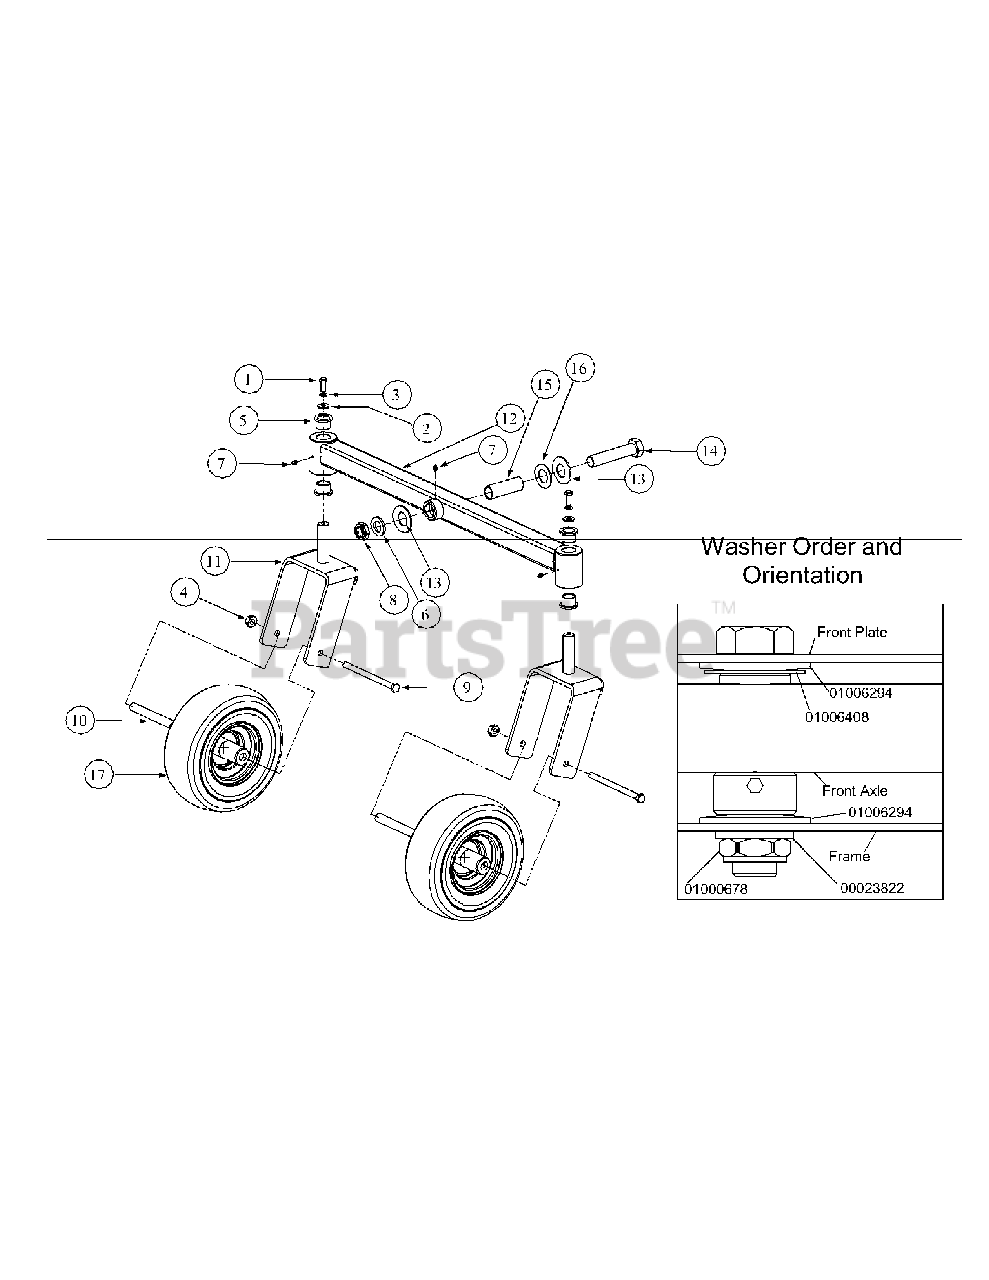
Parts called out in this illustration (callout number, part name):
1	Hex Cap Screw, 3/8-16, 1
2	Flat Washer, .411 x 1.25 x 1.00
3	Lock Washer, 3/8
4	Center Lock Nut, 1/2-20
5	Flange Bearing, 1.013
6	Special Washer
7	Grease Fitting, 1/4-28 x 3/16
8	Jam Lock Nut, 1.0-14
9	Hex Cap Screw, 1/2-2, 7.00
10	Spacer, .51 ID x .75 OD x 5.83 Lg
11	Caster Wheel Bracket Assembly
12	Narrow Front Axle Assembly
13	Belle Washer, 1.25 ID x 2.500 OD x .1
14	Hex Cap Screw, 1-14 x 5.0
15	Spacer, 1.005 ID x 1.25 OD x 3.6
16	Flat Washer, 1.25 ID x 2.25 OD x .0
17	Wheel Assembly, 11 x 4-5.00
